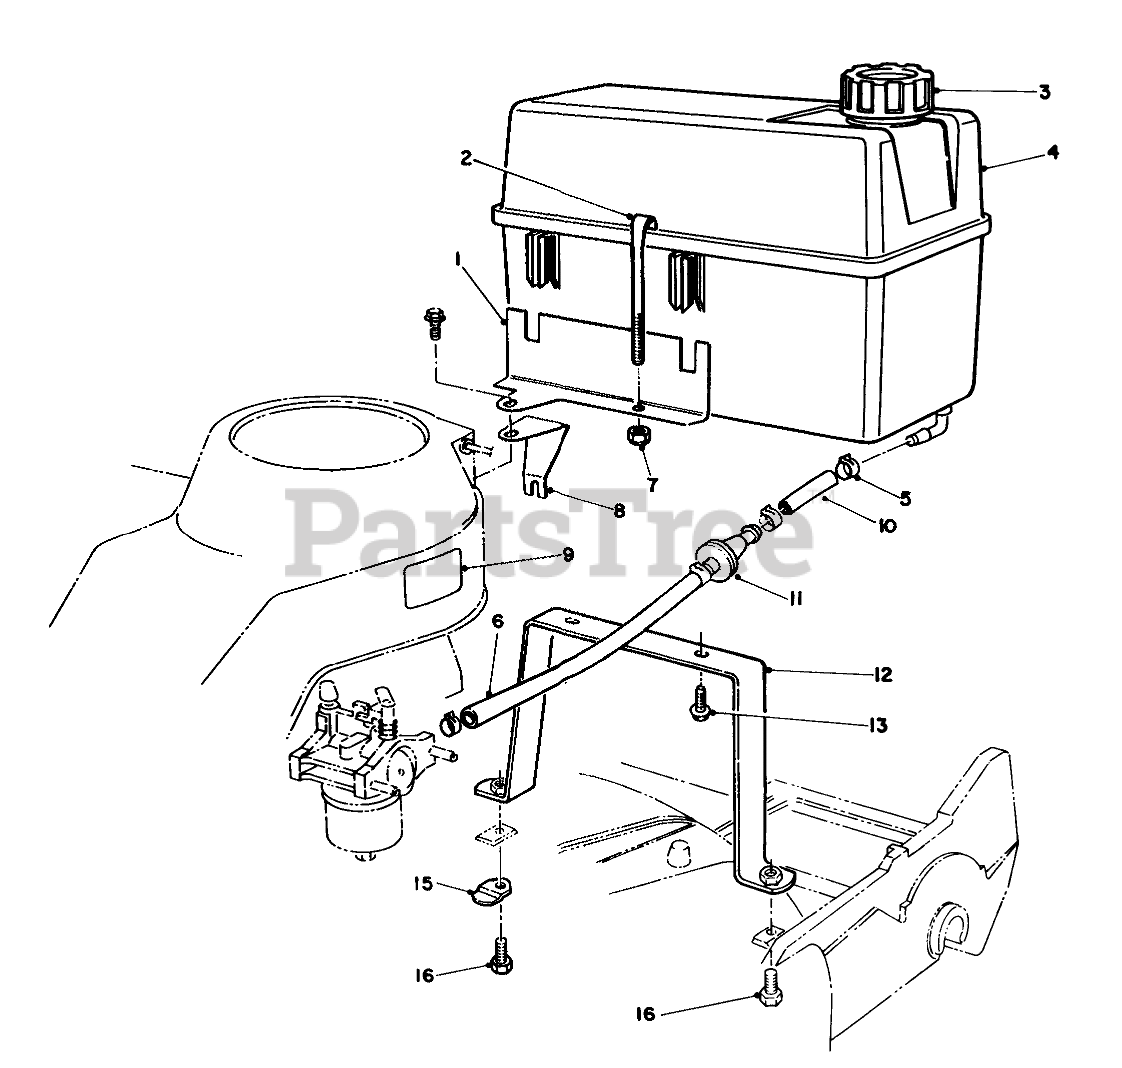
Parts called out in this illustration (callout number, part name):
1	Bracket Tank
2	RETAINER - FUEL TANK
3	GAS CAP ASM
4	Tank-Gas
5	CLAMP-FUEL LINE
6	HOSE-FUEL
7	NUT-LOCK, NI
8	Support-Bracket
9	DECAL - FUEL
10	LINE-GAS
11	FILTER-FUEL
12	Base-Tank
13	SCREW-HWH
15	SHIELD-RETAINER
16	SCREW-HH
